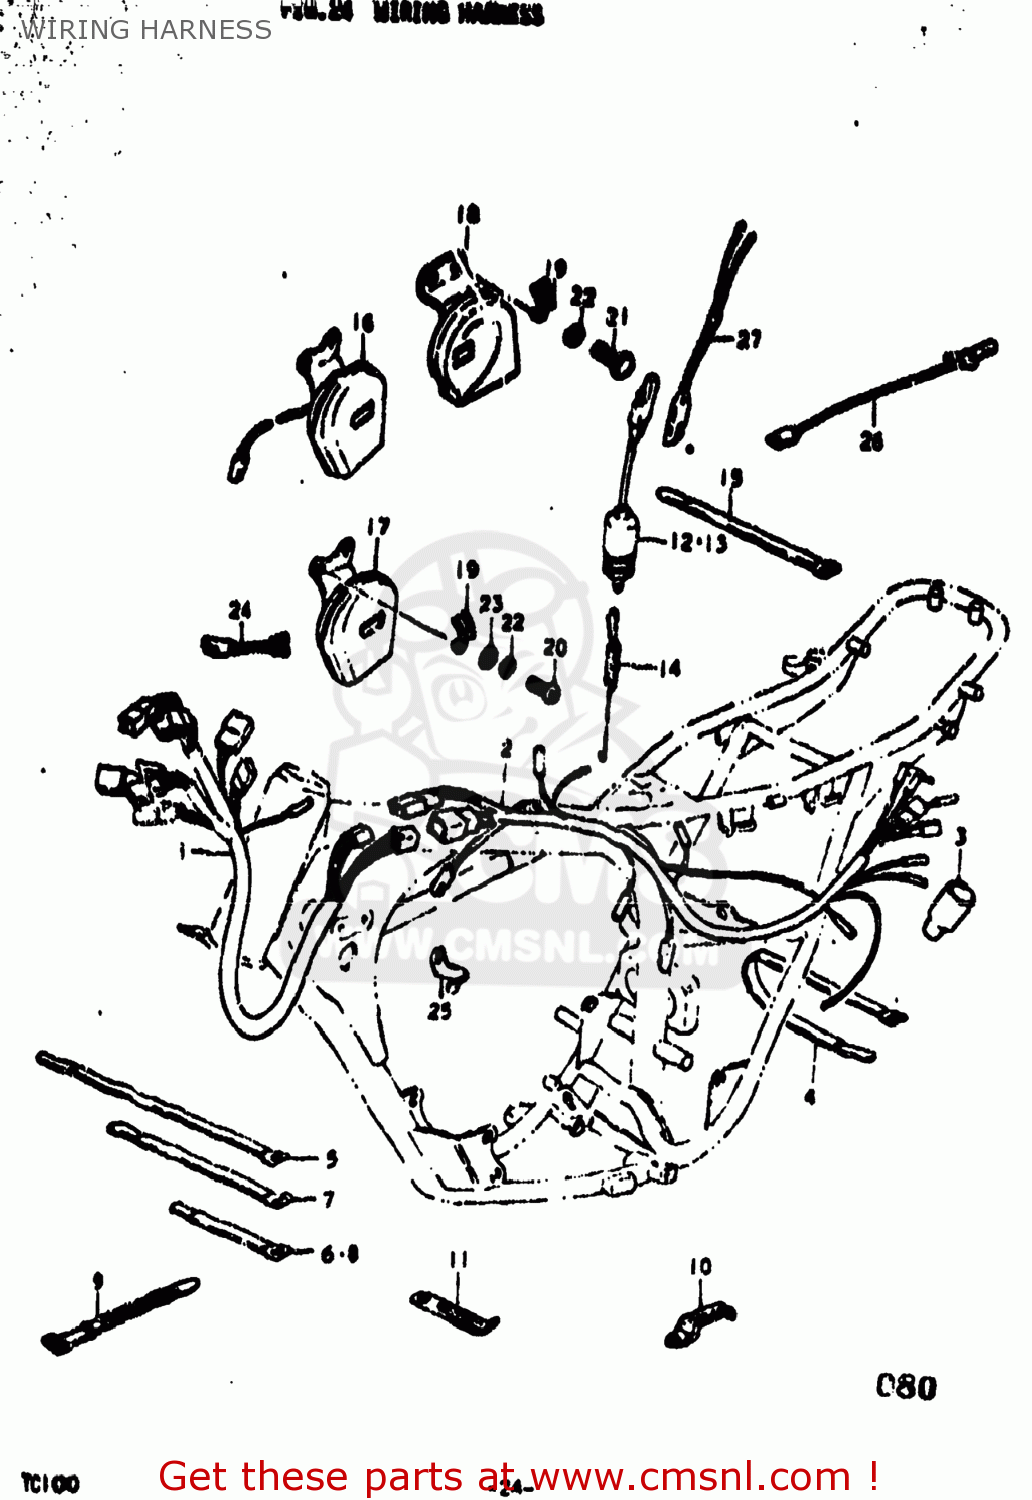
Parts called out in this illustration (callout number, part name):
1	HARNESS,WIRING
2	HARNESS,WIRING NO.2
3	COVER,WIRING HARNESS
4	CLAMP(L:250)
5	CLAMP
6	CLAMP
7	CLAMP
8	CLAMP
9	CLAMP(L:120)
10	CLAMP
11	CLAMP
12	SWITCH ASSEMBLY,STOP LAMP
13	SWITCH ASSY,BRAKE LAMP
14	SPRING
15	CLAMP
16	HORN ASSEMBLY
17	HORN ASSY
18	HORN ASSY
19	CLAMP
20	SCREW 6X12
21	BOLT
22	LOCK WASHER
23	WASHER
24	WIRE
25	CLIP,BRAKE CABLE
26	WIRE,WIRING HARNESS LEAD
27	WIRE
